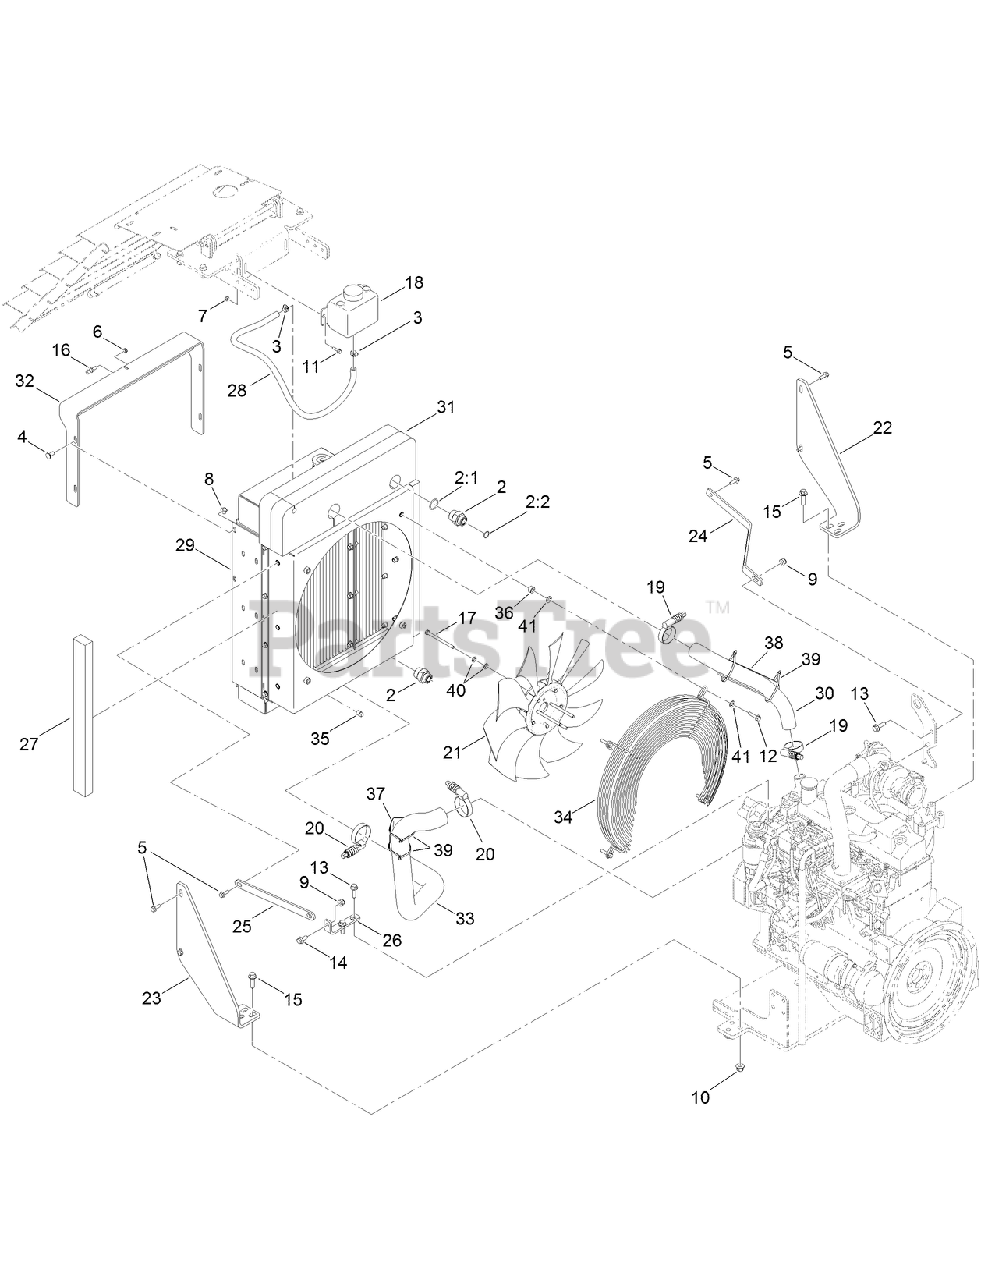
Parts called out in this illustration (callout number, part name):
2	FITTING-STR
2:1	O-RING
2:2	O-RING
3	CLAMP-WORM
4	BOLT-CARR
5	SCREW-HHF
6	NUT-LOCK, NI
7	NUT-HF
8	NUT-HF, NI
9	NUT-LOCK, NI
10	NUT-LOCK, HHF
11	SCREW-HHF
12	SCREW-HHF
13	SCREW-HHF
14	SCREW-HHF
15	SCREW-HHF
16	STUD-BALL
17	SCREW-HH
18	TANK-Overflow
19	CLAMP-TORQUE, CONSTANT
20	CLAMP-TORQUE, CONSTANT
21	FAN-19 INCH (10-BLADE)
22	BRACKET-MOUNT, RADIATOR
23	BRACKET-MOUNT, RADIATOR
24	STRAP-RADIATOR
25	STRAP-RADIATOR
26	PLATE-MOUNT, STRAP
27	SEAL-FOAM
28	HOSE-COOLANT, OVERFLOW
29	COOLER ASM
30	HOSE-UPPER, RADIATOR
31	FOAM-RADIATOR, UPPER
32	SHOCK MOUNT ASM
33	HOSE-LOWER, RADIATOR
34	GUARD-Fan
35	PLUG-PIPE, SQH
36	SPACER-NOMINAL, 10.5mm
37	PROTECTOR-HOSE
38	PROTECTOR-HOSE, 8 INCH
39	TIE-CABLE
40	WASHER-PLAIN
41	WASHER-PLAIN
